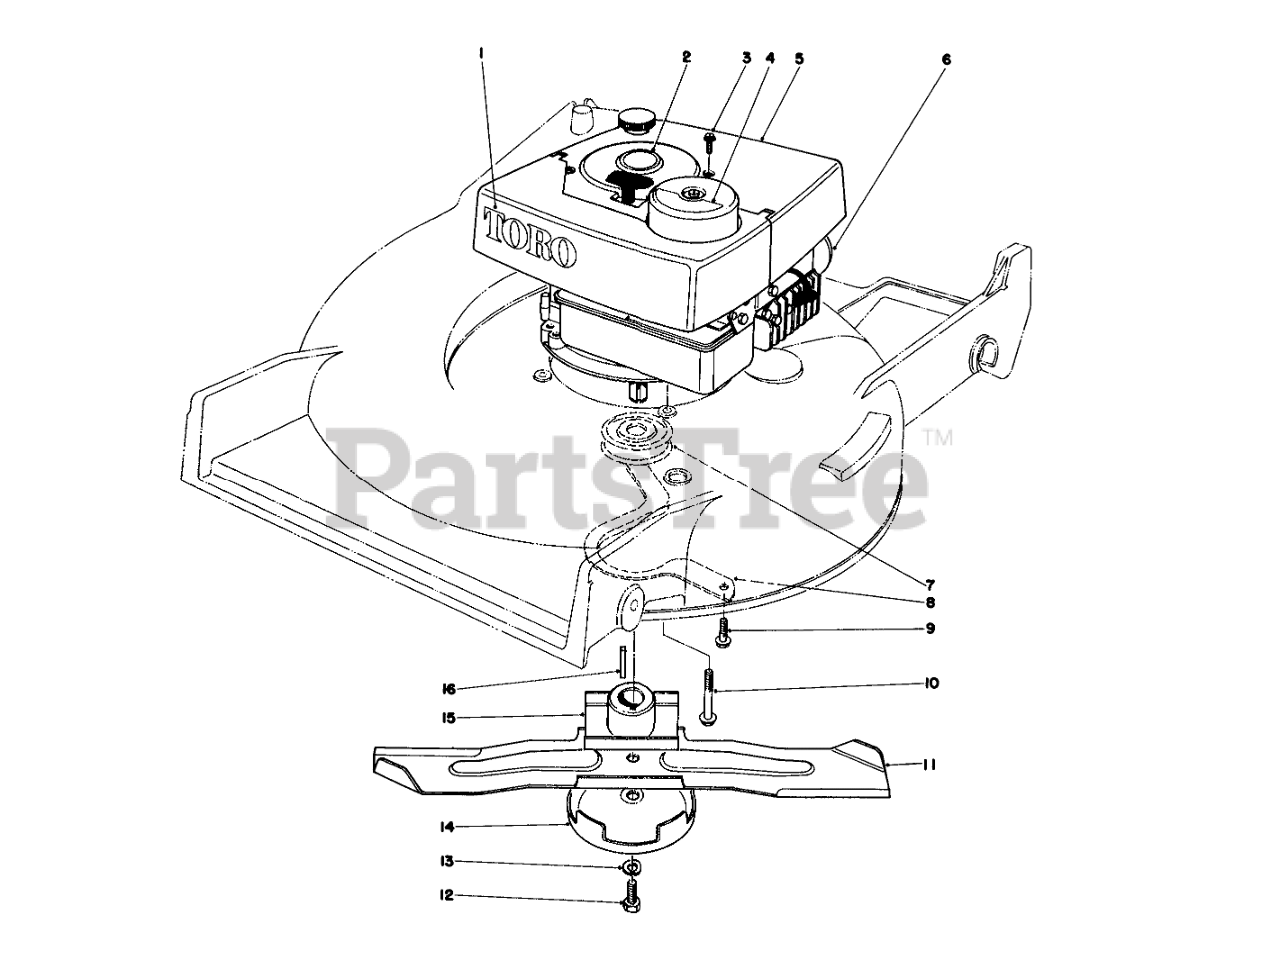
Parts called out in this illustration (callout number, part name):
1	Decal Toro
2	Decal-Shroud
3	8X1/2 SELF TAP SCREW
4	Decal Air Filter
5	SHROUD
6	Engine
7	DRIVER PULLEY
8	Belt Guide
9	Screw
10	SCREW-HWHTF
11	Blade
12	SCREW-BLADE
13	WASHER-LOCK
14	Anti Scalp Cup
15	Blade Retainer
16	Key Square
